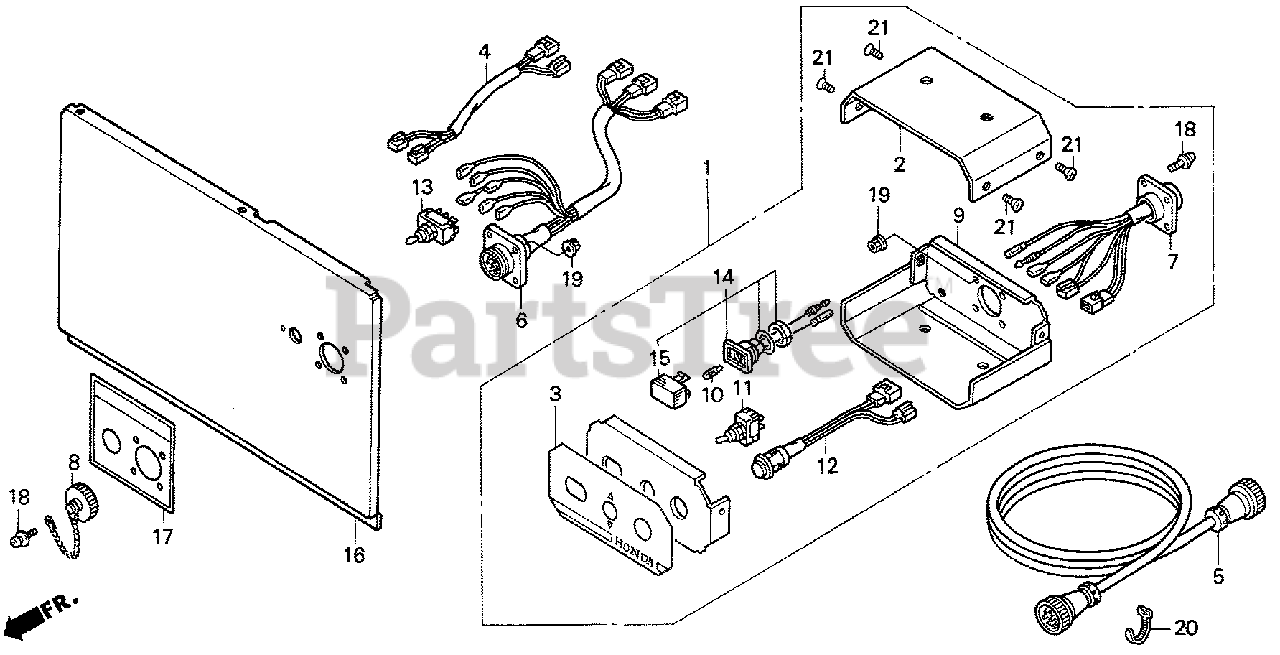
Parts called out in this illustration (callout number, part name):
1	BOX ASSY., REMOTE CONTROL *R8* Use from Frame SN 1001725.
2	COVER (UPPER) Use from Frame SN 1001725.
3	PLATE, SWITCH & INDICATOR Use from Frame SN 1001725.
4	SUB-WIRE HARNESS ASSY. Use from Frame SN 1001725.
5	CABLE, REMOTE CONTROL (15M) Use from Frame SN 1001725.
6	CONNECTOR ASSY., MAIN Use from Frame SN 1001725.
7	CONNECTOR ASSY., BOX Use from Frame SN 1001725.
8	COVER, CONNECTOR Use from Frame SN 1001725.
9	CASE, SWITCH Use from Frame SN 1001725.
10	BULB, WEDGE BASE (12V/2W) Use from Frame SN 1001725.
11	SWITCH ASSY., MAIN Use from Frame SN 1001725.
12	SWITCH ASSY., STARTER Use from Frame SN 1001725.
13	SWITCH ASSY., SELECT Use from Frame SN 1001725.
14	SOCKET ASSY., LAMP (GREEN) Use from Frame SN 1001725.
15	LENS (GREEN) Use from Frame SN 1001725.
16	COVER, GENERATOR MAINTENANCE Use from Frame SN 1001725.
17	MARK, REMOTE CONTROL (E) Use from Frame SN 1001725.
18	SCREW-WASHER (3X12) Use from Frame SN 1001725.
19	NUT, FLANGE (3MM) Use from Frame SN 1001725.
20	TIE, CABLE Use from Frame SN 1001725.
21	SCREW, FLAT (4X8) Use from Frame SN 1001725.
